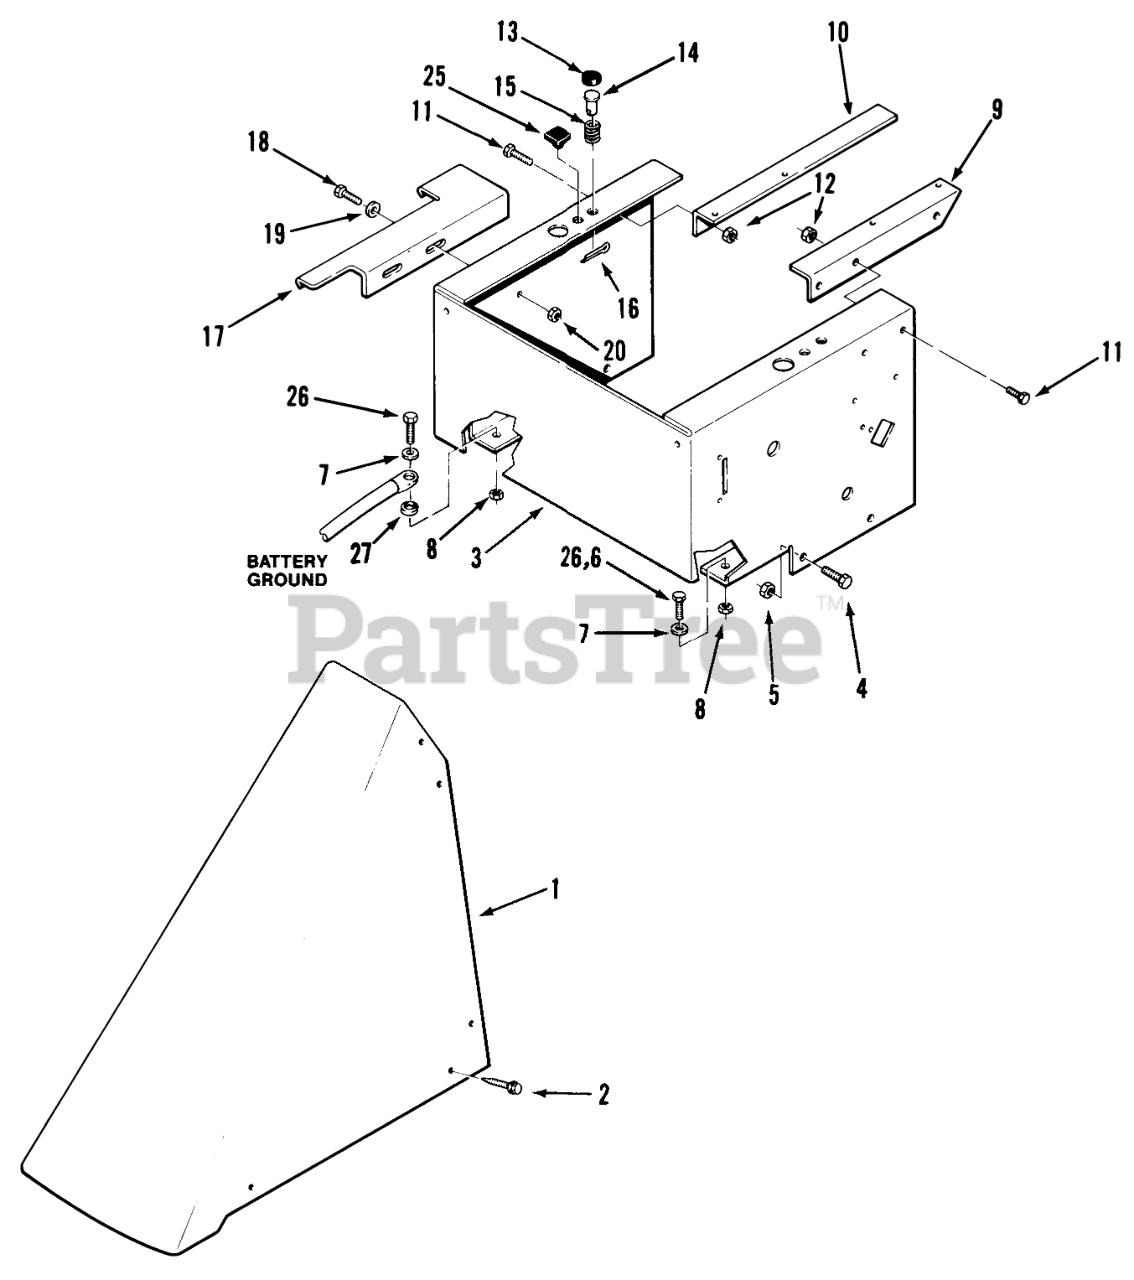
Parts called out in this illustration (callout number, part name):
1	COVER CONSOLE R
2	HEX WASHER STS
3	Seat Support
4	Bolt 3/8-16 x 3/4 GRD 5
5	NUT
6	Bolt
7	WASHER 5/16 SAE
8	Nut
9	ANGLE TANK SUPP. R
10	ANGLE TANK SUPP. R
11	Bolt
12	Nut
15	SPRING
16	Cotter Pin
17	PLATE SHIFT R
18	Bolt
19	WASHER 5/16 SAE
20	Nut
25	BUMPER SJ5514 BLACK
26	Bolt
